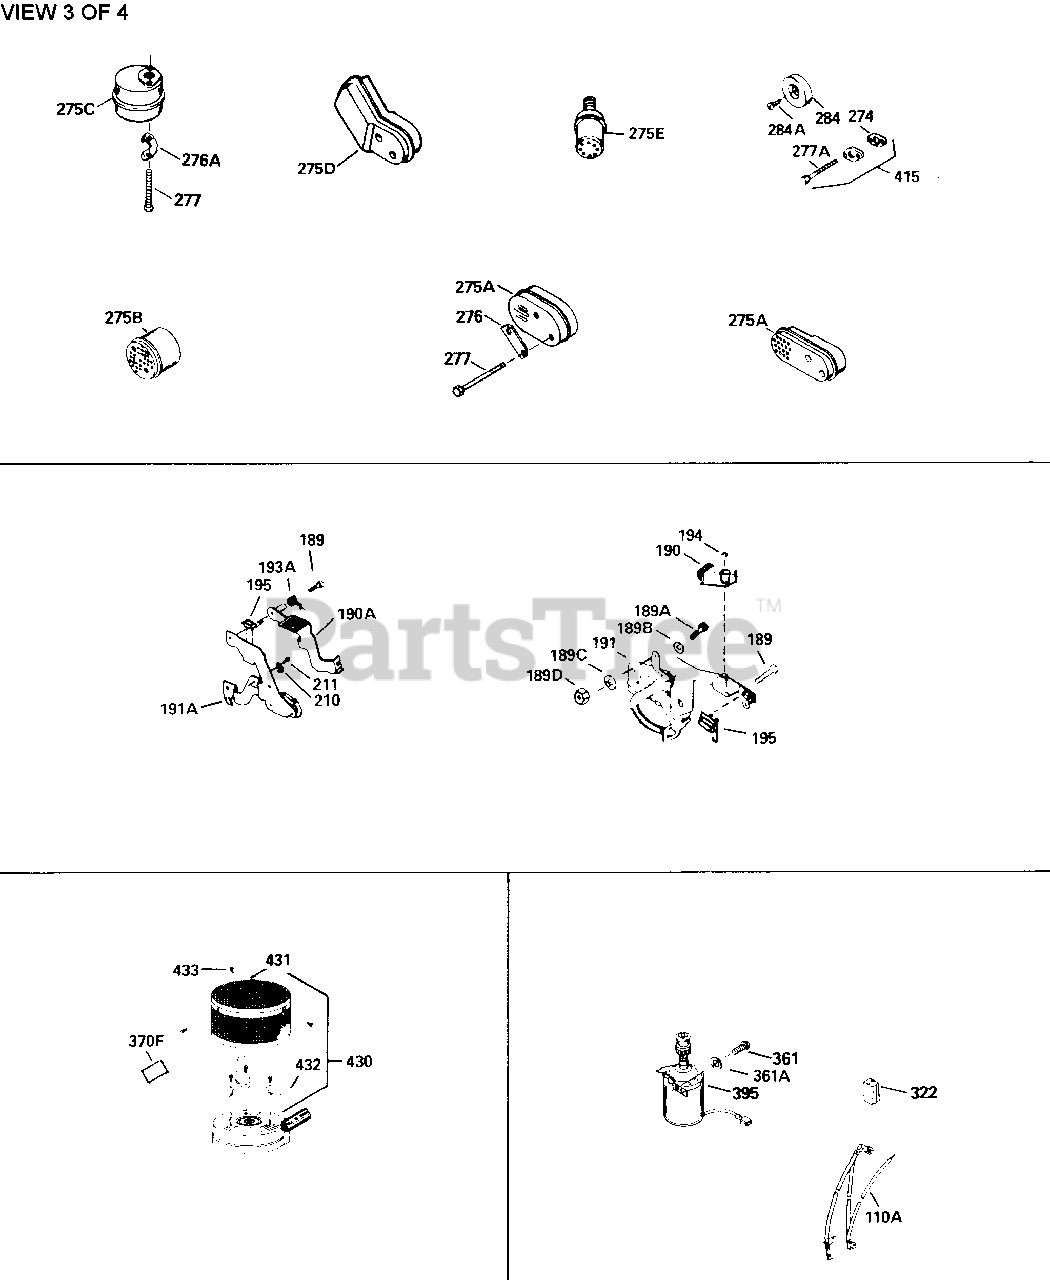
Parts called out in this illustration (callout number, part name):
274	* Gasket, Exhaust (Use as required)
277	Screw, 1/4-20 x 2-1/4"
277A	Screw, T-30, 1/4-20 x 1/2"
370F	Decal, Instruction (Optional)
415	Muffler Adap.Kit (Incl. 274,277A) Use as req.
430	Debris Screen Kit (Incl. 370F,431-433 )(Opt.)
431	Debris Screen (Optional)
432	Debris Screen Bracket (Optional)
433	Screw, 8-32 x 1/4" (Optional)
